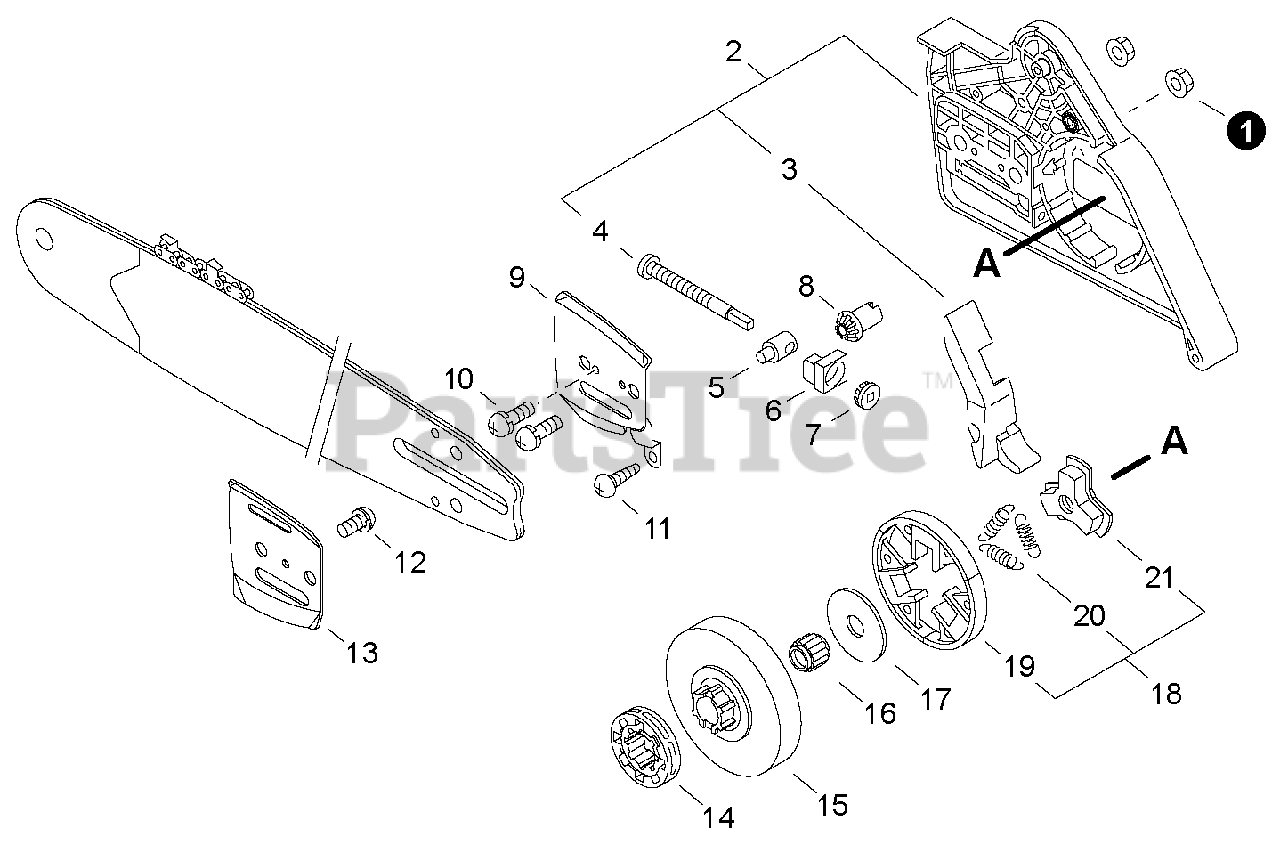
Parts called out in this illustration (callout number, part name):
1	NUT - 8X1.25 -- FLANGE
2	SPROCKET GUARD KIT
3	CUSHION
4	SCREW, TENSIONER
5	TENSIONER, CHAIN
6	COLLAR - 8
7	GEAR - BEVEL
8	GEAR - PINION
9	PLATE, OUTER GUIDE
10	SCREW - 3X6
11	SCREW - 4X10
12	SCREW - 4X8
13	PLATE, GUIDE - INNER
14	SPROCKET, RIM
15	DRUM, CLUTCH
16	BEARING, NEEDLE
17	PLATE, CLUTCH
18	CLUTCH ASSY
19	CLUTCH SHOE SET
20	SPRING, CLUTCH
21	HUB, CLUTCH
